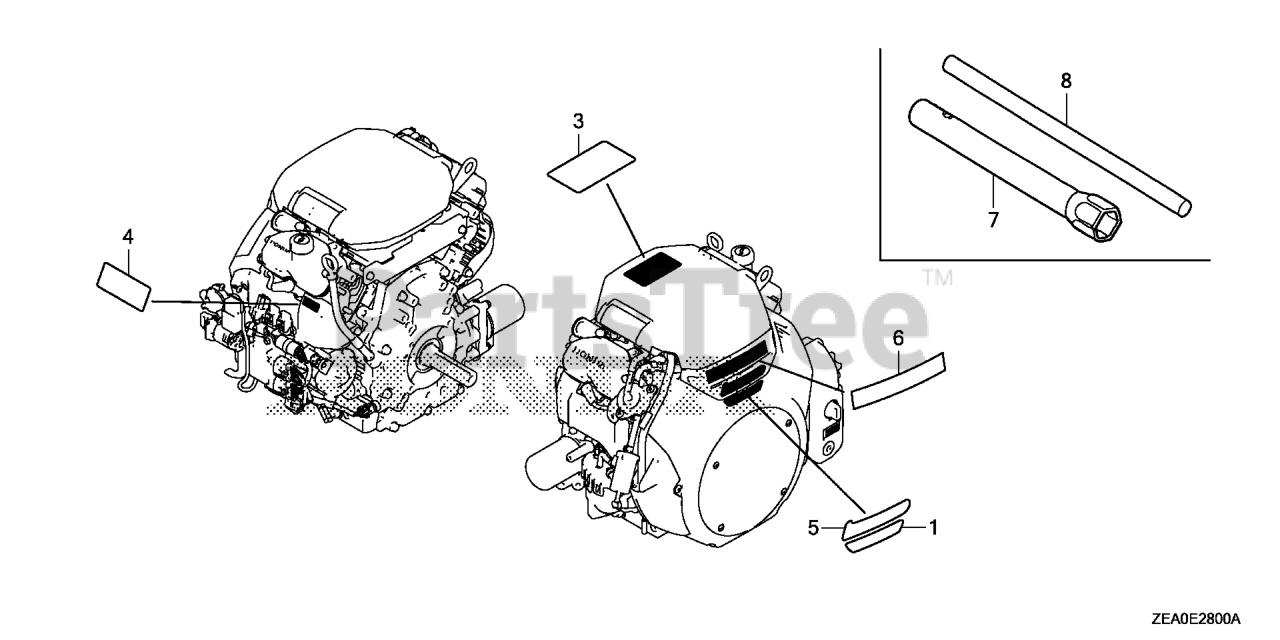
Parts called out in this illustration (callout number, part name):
3	MARK, OPERATOR CAUTION (PICTOGRAPH)
4	LABEL, QR CODE (SERVICE)
5	EMBLEM (GX700)
6	MARK, HONDA
